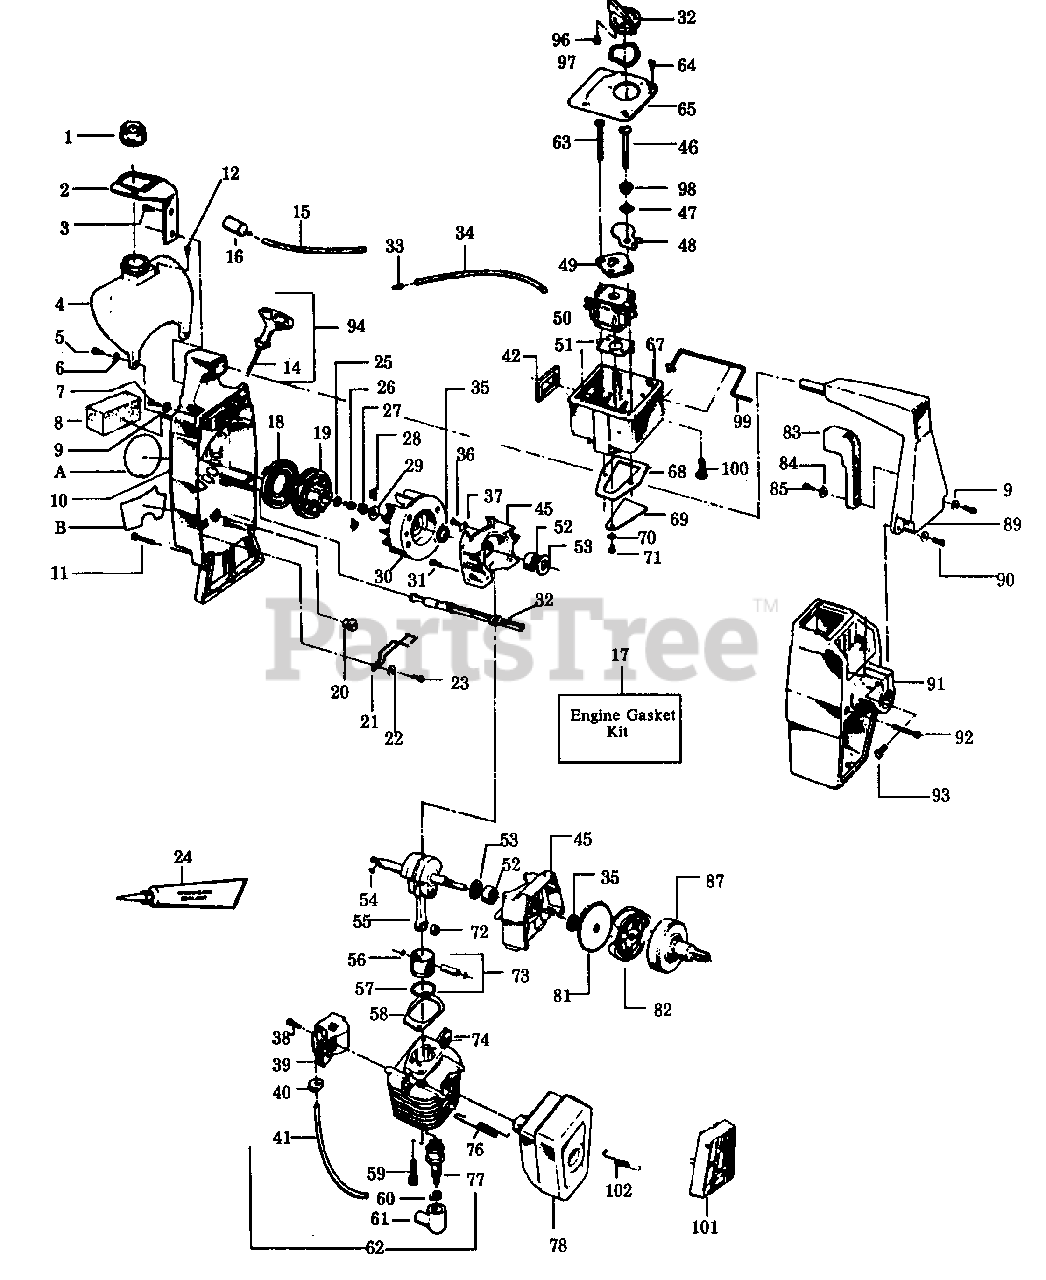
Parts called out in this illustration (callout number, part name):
1	Fuel Cap Ass'y.
2	Fuel Tank Bracket
3	Screw
4	Fuel Tank Ass'y. (Inc.1, 12, 15 & 16)
8	Air Filter
10	Fan Housing
14	Rope Kit
15	Line Kit
16	Fuel Pick-Up Ass'y.
17	Engine Gasket Kit
18	Starter Recoil Spring
19	Starter Pulley
20	Kill Switch Button
21	Kill Switch Spring
24	Crankcase Sealant
26	Screw
27	Flywheel Nut
28	Starter Dog Spring
30	Flywheel Ass'y. (Inc.28)
32	Choke Knob
33	Fuel Line Fitting
34	Carburetor Fuel Line
35	Crankshaft Seal
38	Screw
39	Ignition Module Kit
40	Plug Wire Grommet
41	High Tension Lead Wire
42	Carburetor Case Seal
45	Crankcase Ass'y (Inc.35,52 and Qty. 1 of #31)
46	Carburetor Screw
47	Wave Washer
48	Choke Shutter
49	Guide Plate
50	Carburetor (WA-149)
51	Carburetor Gasket
52	Crankshaft Bearing
53	Crankshaft Thrust Washer
54	Flywheel Key
55	Crankshaft & Rod Ass'y.
56	Wrist Pin Retainer
57	Piston Ring
58	Cylinder Gasket
60	Spark Plug Connector
61	Spark Plug Boot
62	High Tension Lead Ass'y. (Inc.41,60 & 61)
63	Carburetor Screw
65	Carburetor Case Cover
67	Carburetor Case Ass'y.
68	Carburetor Case Crankcase Gasket
69	Reed Valve
70	Reed Valve Washer
72	Wrist Pin Bearing
73	Piston Ass'y. (Inc.56,57 & Pin)
74	Cylinder
76	Muffler Attachment Spring
77	Spark Plug (CJ-14)
78	Muffler Ass'y.
81	Clutch Washer Kit
82	Clutch Ass'y. Kit
83	Throttle Trigger
84	Throttle Washer
87	Drum & Coupling Ass'y.
94	Rope & Handle Starter Ass'y.
99	Throttle Wire
101	Muffler Guard
102	Muffler Spring
A	Starting Instructions Decal
B	Choke/Off Decal
